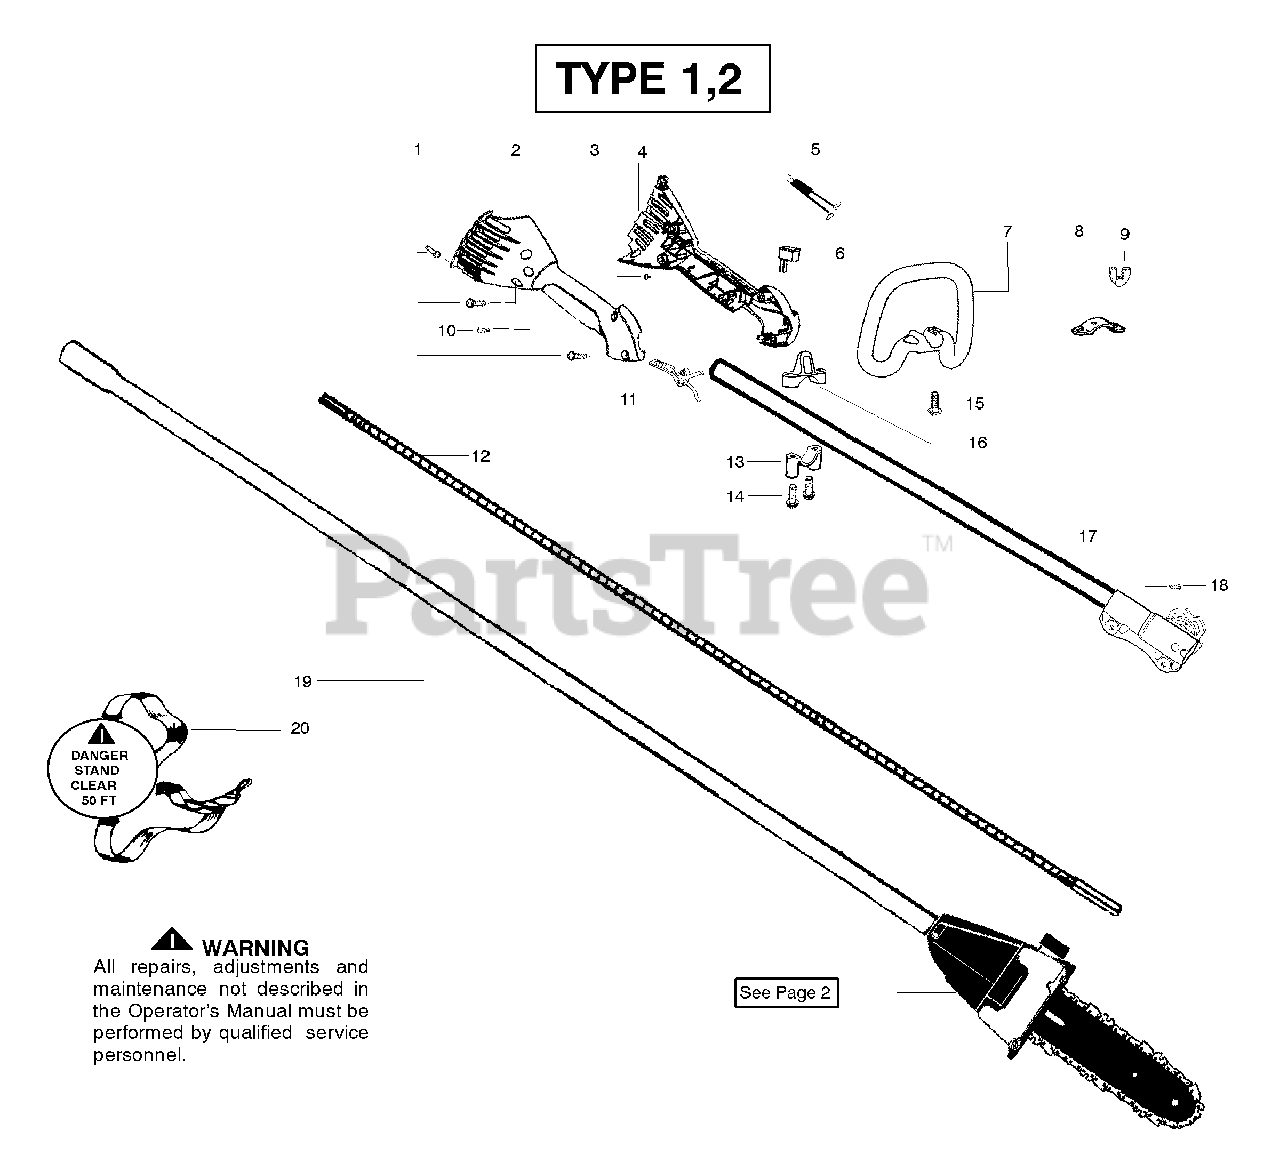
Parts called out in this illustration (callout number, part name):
2	Hsg.-Throttle right
3	Screw-Cable Ret.
4	Hsg.-Throttle left
5	Assy-Wire
6	Kit-Switch
7	Assy-Handle
8	Clamp-Handle
9	Wingnut
10	Screw-Align
11	Trigger-Throttle
12	Flex-Lower
13	Clamp-Lower
16	Clamp-Upper
17	Kit-Upper Shaft
19	Assy-Driveshaft
20	Assy-Shoulder Strap
